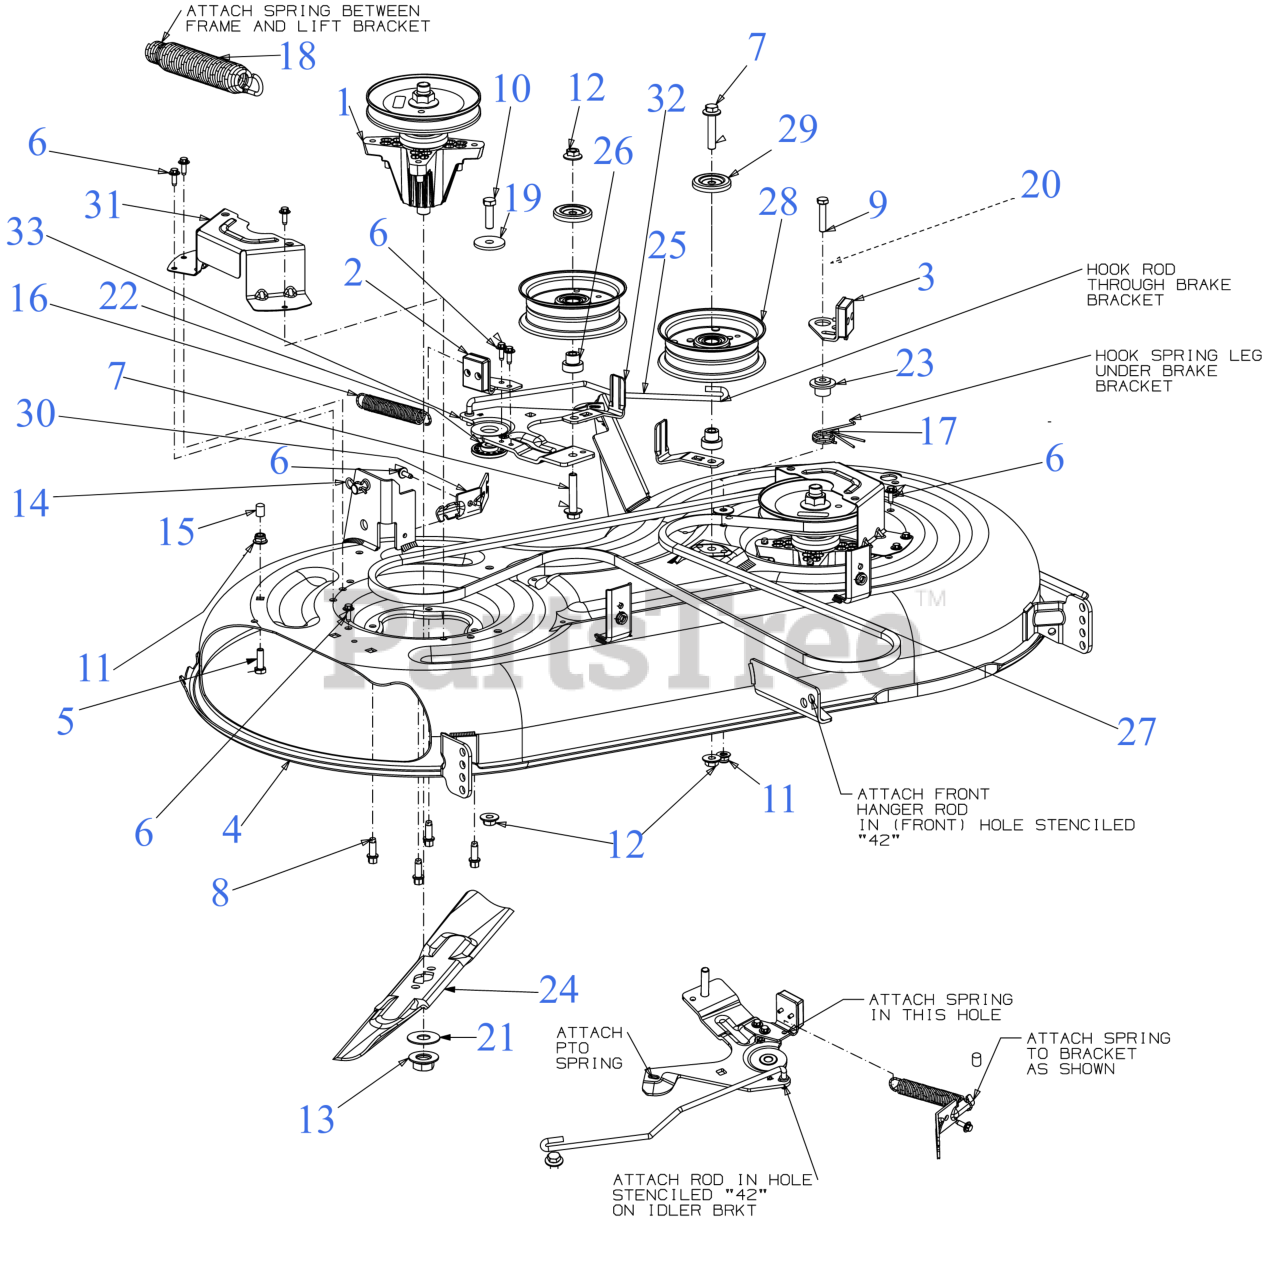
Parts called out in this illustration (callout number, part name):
1	SPINDLE ASSEMBLY (6.3 DIA)
2	DECK BRAKE ASSEMBLY (RH)
3	DECK BRAKE ASSEMBLY
4	42" DECK SHELL (2W)
5	SCREW 5/16-18 x 1.0 GR5
6	SCREW M6-1 x .625
7	SCREW 3/8-16 x 2.0
8	SCREW 5/16-18 x .875
9	SCREW 5/16-18 x 1.5 LG
10	SCREW 3/8-16 x 1.25 GR5
11	FLANGE LOCK NUT 5/16-18
12	FLANGE LOCK NUT
13	HEX FLANGE NUT 5/8-18 GR5
14	BOW TIE COTTER PIN
16	EXTENSION SPRING
17	TORSION SPRING
18	LIFT ASSIST SPRING (SMALL)
19	FLAT WASHER .390x1.500x.134
20	FLAT WASHER 344X1.00
21	FLAT WASHER .635X1.585X.062 HDN
22	SHOULDER SPACER
23	DOUBLE SHOULDER SPACER .750 x .135
24	21.23" BLADE (2IN1) (S SHAPE CENTER HOLE)
24	Cub Cadet 42" HI LIFT BLADE SET (S SHAPE CENTER HOLE)
24	21.23" XTREME BLADE (2IN1) (S SHAPE CENTER HOLE)
24	Cub Cadet 42" XTREME BLADE SET (S SHAPE CENTER HOLE)
24	21.23" LOW LIFT BLADE (S SHAPE CENTER HOLE)
24	Cub Cadet 42" LOW LIFT BLADE SET (S SHAPE CENTER HOLE)
25	DECK BRAKE ROD
26	SHOULDER SPACER
27	V-BELT A SEC x 99.75
27	Cub Cadet 42" DECK DRIVE BELT
27	Genuine Factory Parts 42" DECK DRIVE BELT
28	IDLER PULLEY 4.50" DIA
29	IDLER PULLEY CAP
30	ENGAGEMENT CABLE BRACKET
33	42" IDLER BRACKET PIVOT 42"
